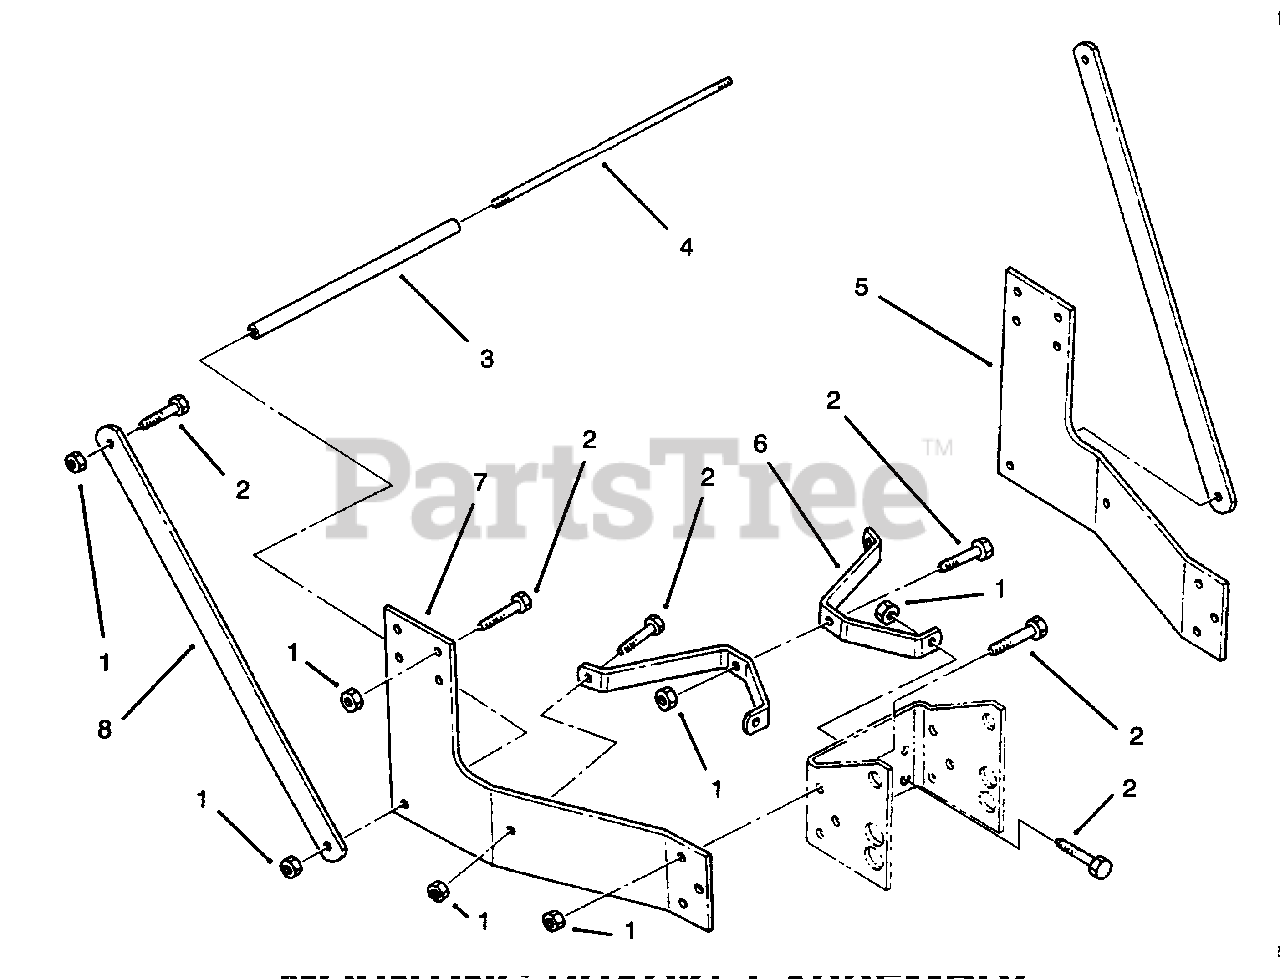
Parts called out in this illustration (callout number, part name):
1	Nut-Lock
2	Screw-Hex Hd. Cap
3	Tube-Support
4	Rod-Support
5	Bracket-L.H.
6	Brace-Center
7	Bracket R.H.
8	Brace
